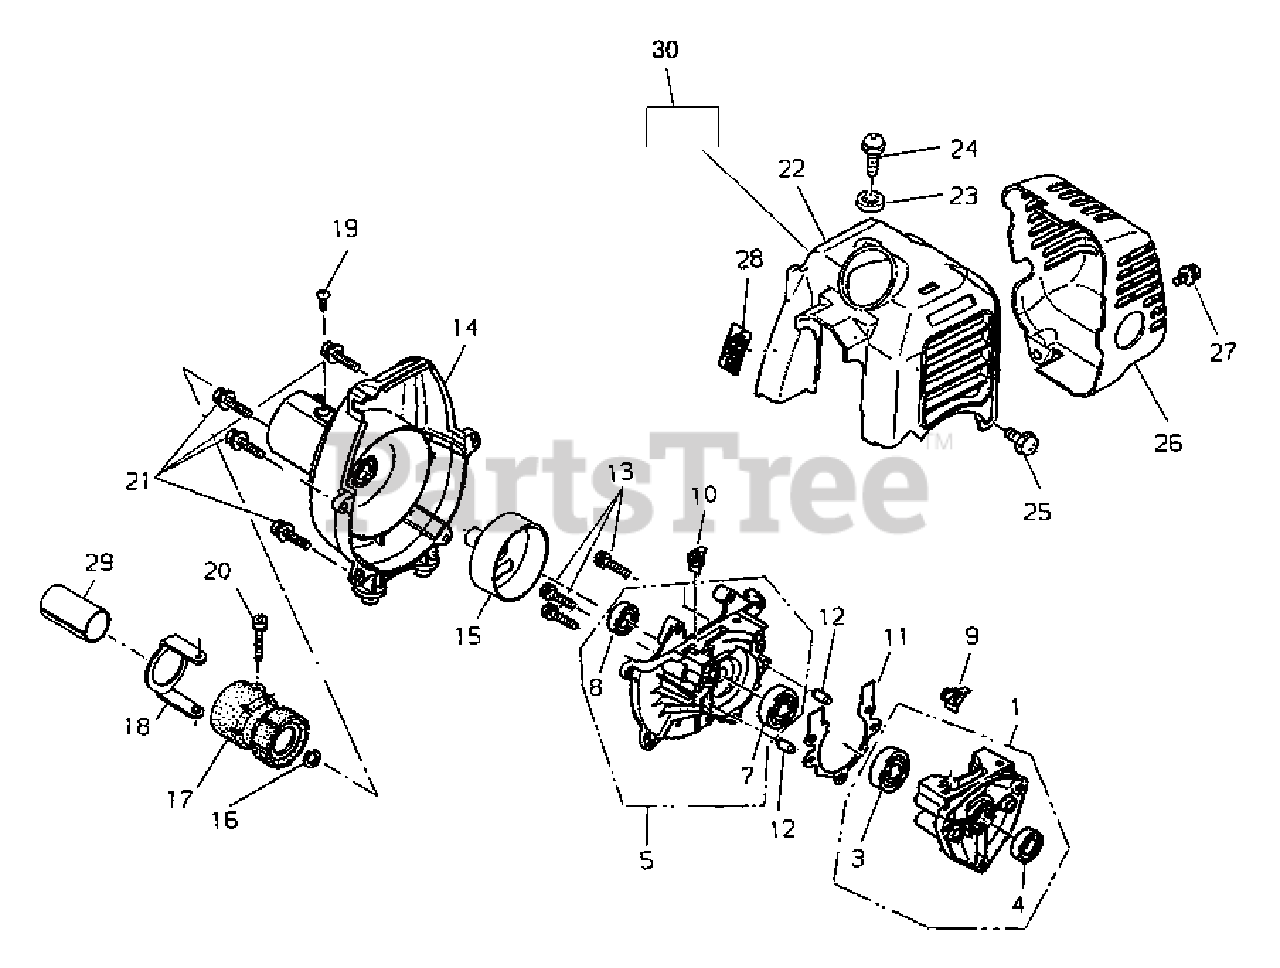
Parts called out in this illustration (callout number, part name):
1	CRANKCASE ASSY - REAR
3	BEARING, BALL
4	SEAL, OIL
5	CRANKCASE ASSY - FRONT
7	BEARING, BALL
8	SEAL, OIL
11	GASKET
12	ROLLER
14	CASE, FAN
15	DRUM, CLUTCH
16	RING, RETAINING
17	CUSHION
18	BRACKET
22	COVER, ENGINE
23	INSULATOR
26	COVER, MUFFLER
28	LABEL - FEATURE
30	LABEL
